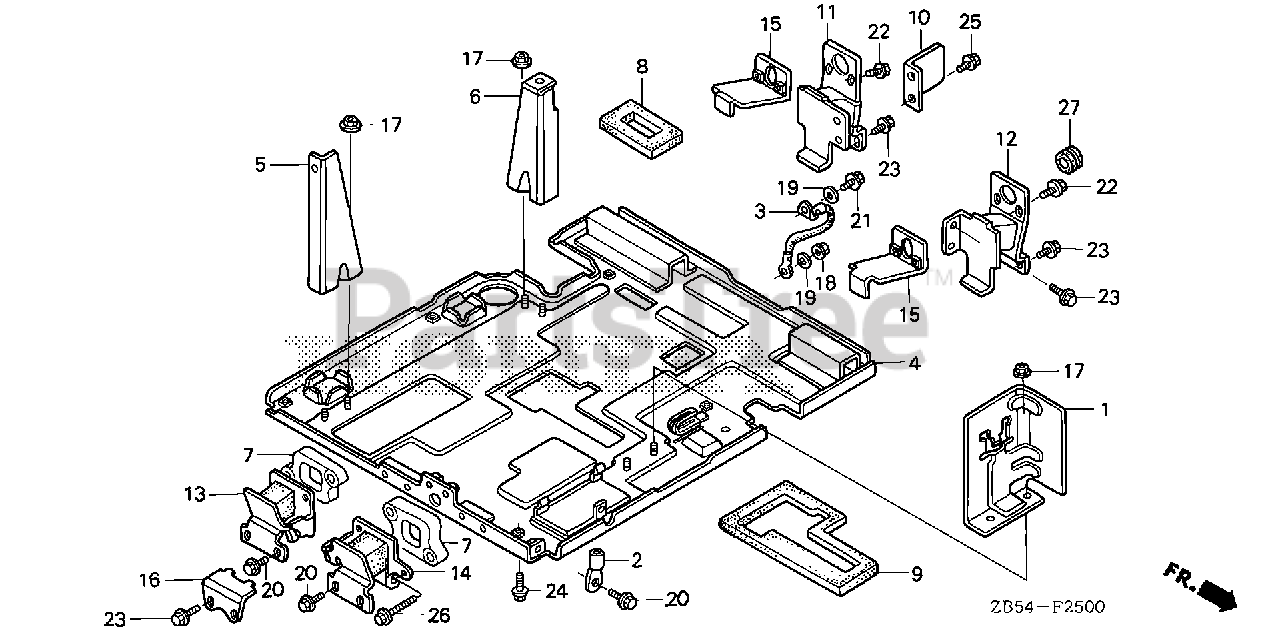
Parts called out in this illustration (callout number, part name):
1	SUPPORT, RESERVE TANK
2	TERMINAL, LA (8MM)
3	WIRE, GROUND
4	BED, FRAME
5	STAND, R. SHROUD
6	STAND, L. SHROUD
8	SEAL, MOTOR STAY
9	SEAL, FR. HOUSING
10	STOPPER, ENGINE MOUNT SIDE
11	RUBBER, R. FR. MOUNT
12	RUBBER, L. FR. MOUNT
13	RUBBER, R. RR. MOUNT
14	RUBBER, L. RR. MOUNT
15	STOPPER, ENGINE MOUNT RUBBER
16	STOPPER, GENERATOR MOUNT
17	NUT, FLANGE (6MM)
18	NUT, FLANGE (8MM)
19	WASHER, STAR
20	BOLT, FLANGE (8X16) Use from Engine SN 1000016.
21	BOLT, FLANGE (8X20) Use up to Engine SN 1609606.
22	BOLT, FLANGE (6X16) Use from Engine SN 2056820.
23	BOLT, FLANGE (8X16) Use from Engine SN 1000016.
24	BOLT, FLANGE (8X16) Use from Engine SN 1000016.
25	BOLT, FLANGE (8X25)
26	BOLT, FLANGE (8X16) Use up to Frame SN 1008045.
26	BOLT, FLANGE (8X16) Use from Engine SN 1000016.
27	RUBBER B, STEP MOUNTING
